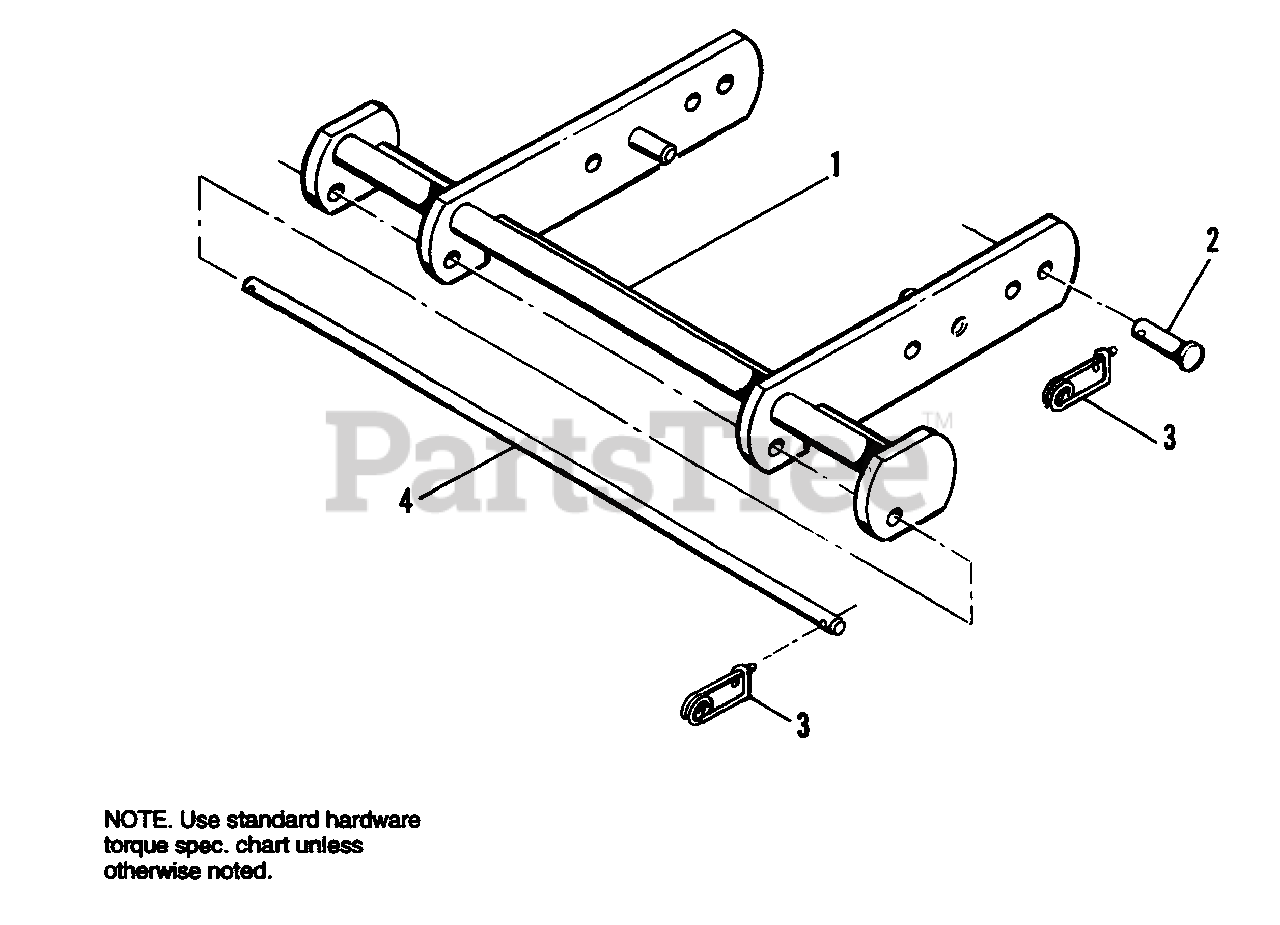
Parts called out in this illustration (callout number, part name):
1	CARRIER ASSY.
2	PIN, Clevis
3	CLIP, Pin, Safety
4	ROD, Weight Hold Down
